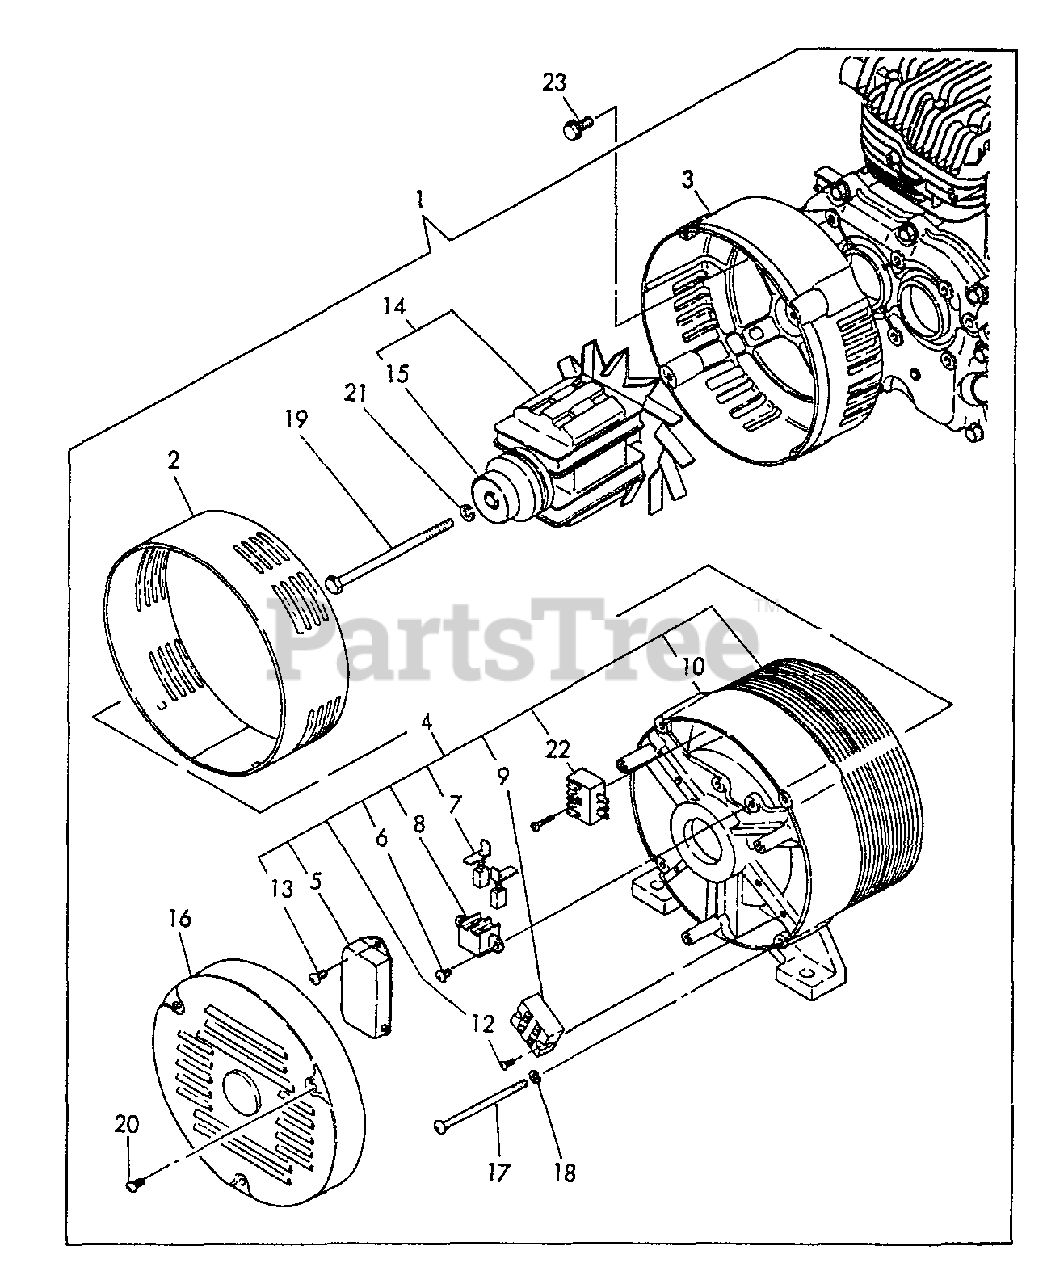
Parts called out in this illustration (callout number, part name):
1	GENERATOR 3.0 KVA
2	CLAMP
3	COVER, FRONT
4	STATOR ASSY
5	A.V.R.
6	SCREW - 5×14
7	BRUSH
8	HOLDER, BRUSH
9	TERMINAL
10	COVER - REAR
12	SCREW - 5×14
13	SCREW - 4×14
14	ROTOR ASSY
15	BEARING, BALL
16	COVER, END
17	BOLT, THROUGH
18	LOCKWASHER - 6
19	BOLT
20	SCREW - 4×8
21	LOCKWASHER - 10
22	RECTIFIER
23	BOLT - 8×20 -- PLATED
